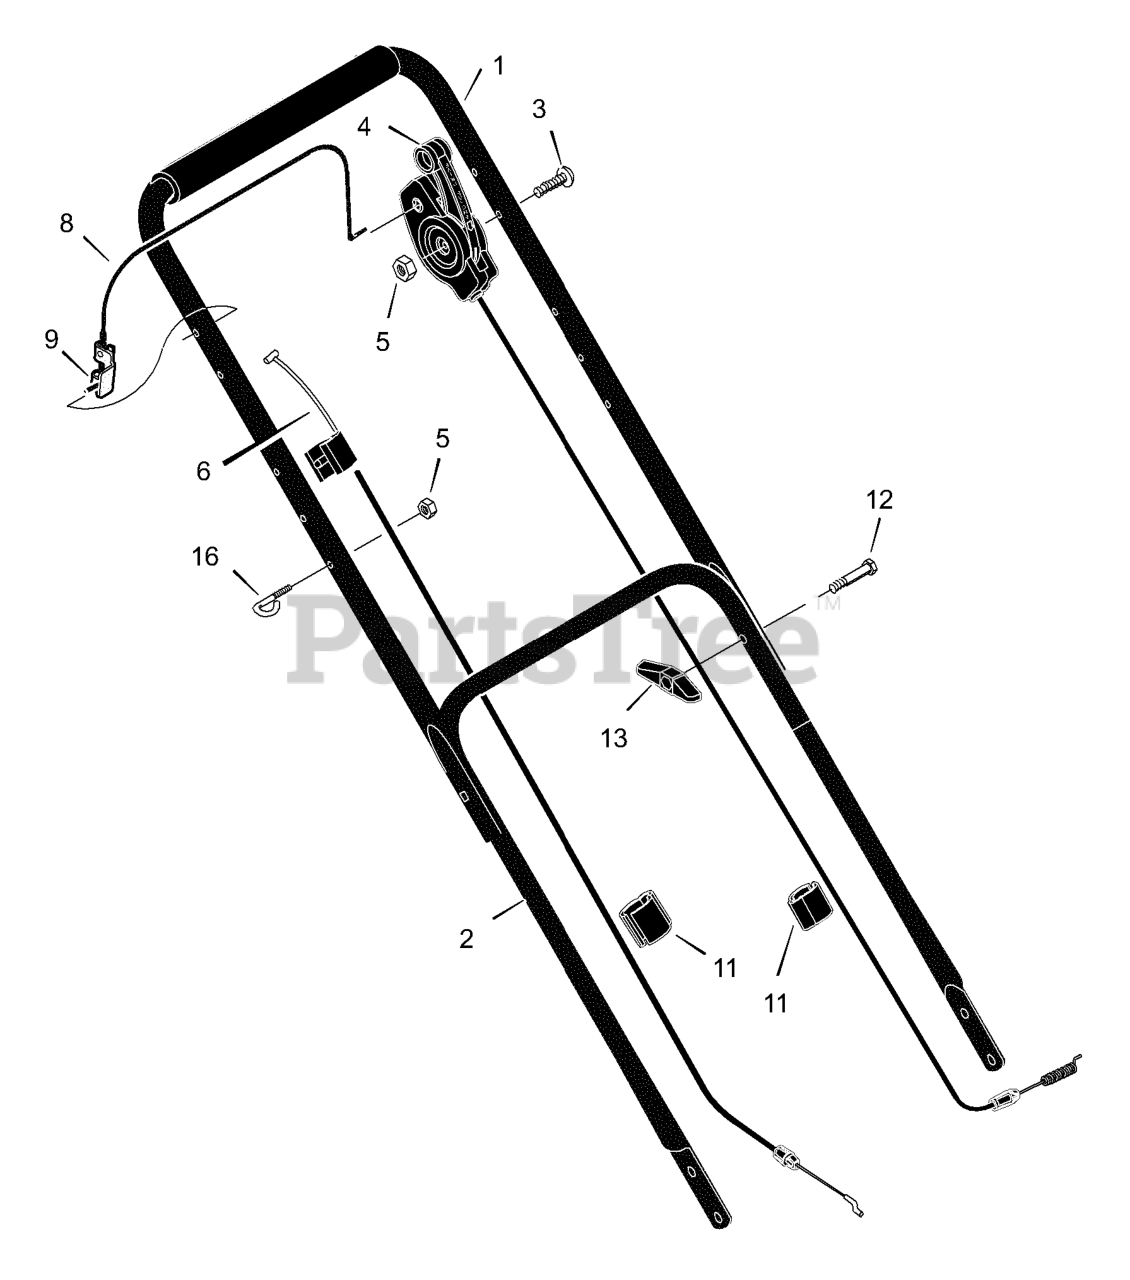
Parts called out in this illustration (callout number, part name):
1	Handle, Upper (Black)
2	Handle, Lower (Black)
4	Control, Drive
5	Locknut
6	Cable, Stop
8	Lever, Stop
9	Bracket, Stop Lever
11	Fastener, Single Cable
13	Knob
16	Guide, Rope
